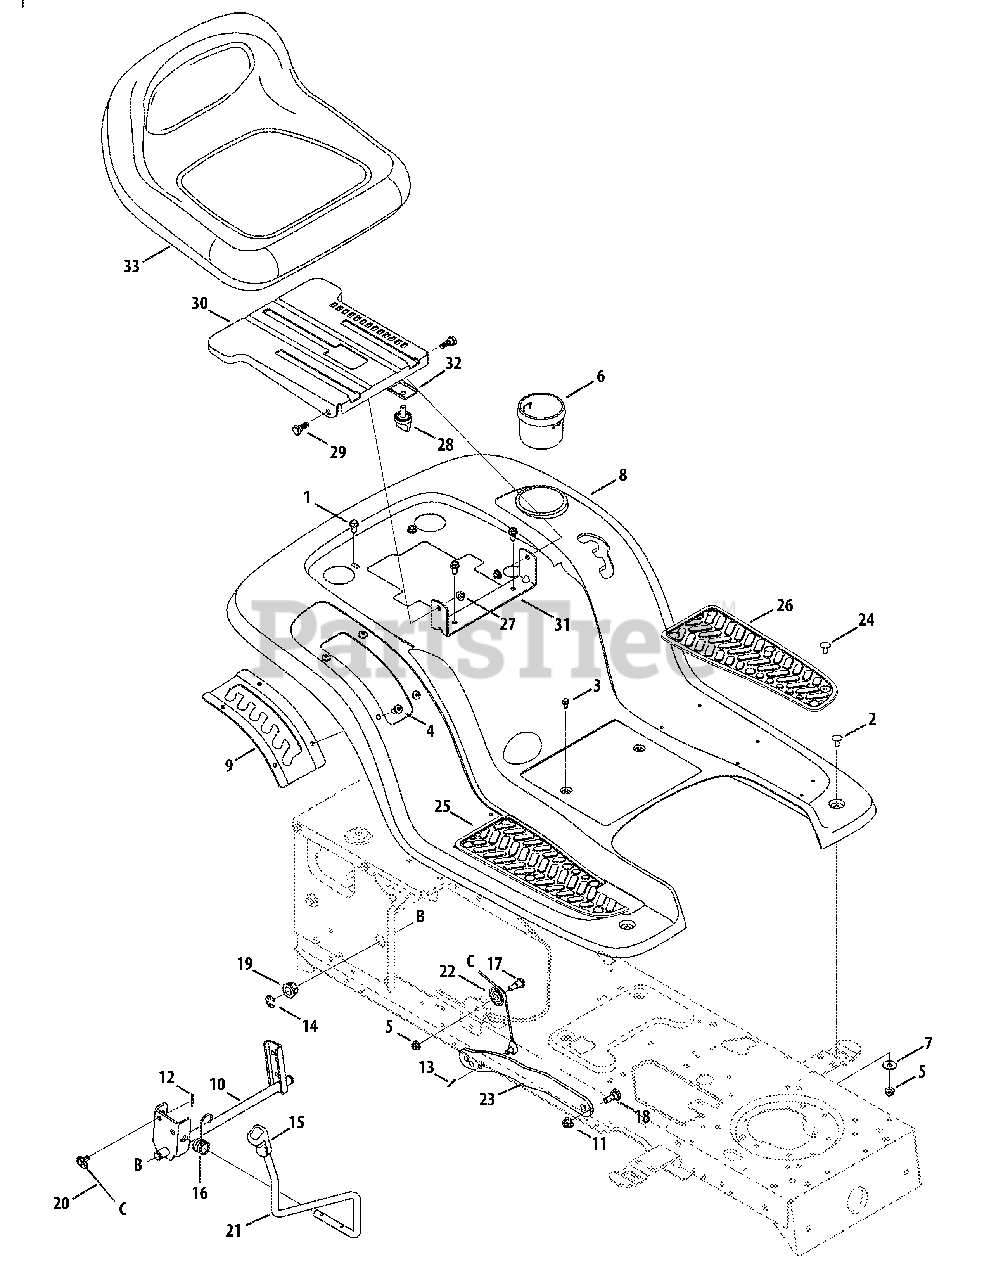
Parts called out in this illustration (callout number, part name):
1	Screw, 5/16-18, 0.750x
2	Carriage Bolt, 5/16-18 x .750
3	Screw, 1/4-20, 0.500
4	Screw, 5/16-18, 0.750
5	Nut, Flange Lock, 5/16-18, GrF
6	Cup Holder
7	Washer, Flat,.344 x 1.0 x.063
8	Fender (10-Style)
9	Deck Lift Plate (10-Style)
10	Deck Lift Shaft Assembly
11	Nut, Flange Lock, 3/8-16, GrF
12	Pin, Cotter,.072 Dia. x 1.13
13	Pin, Cotter, 3/32, 1.0
14	Ring, E Type,.625 Dia.
15	Grip, Handle, 1/2
16	Spring, Torsion
17	Screw, 5/16-18 x.620 Gr2
18	Screw, Shld,.50 x.27, (46" & 50" Deck)
19	Bearing, Hex Flange
20	Cable, Lift, 16.16
21	Handle, Lift
22	Pulley, Roller
23	Arm, Lift (46" Deck)
24	Ratchet Clip
25	RH Foot Pad
26	LH Foot Pad
27	Nut, Flange Lock, 5/16-18, Gr5
28	Knob, 3/8-16
29	Screw, Shoulder,.437 x.268
30	Seat Mounting Bracket
31	Seat Pivot Bracket
32	Seat Adjustment Knob Bracket
33	Medium Back Seat
